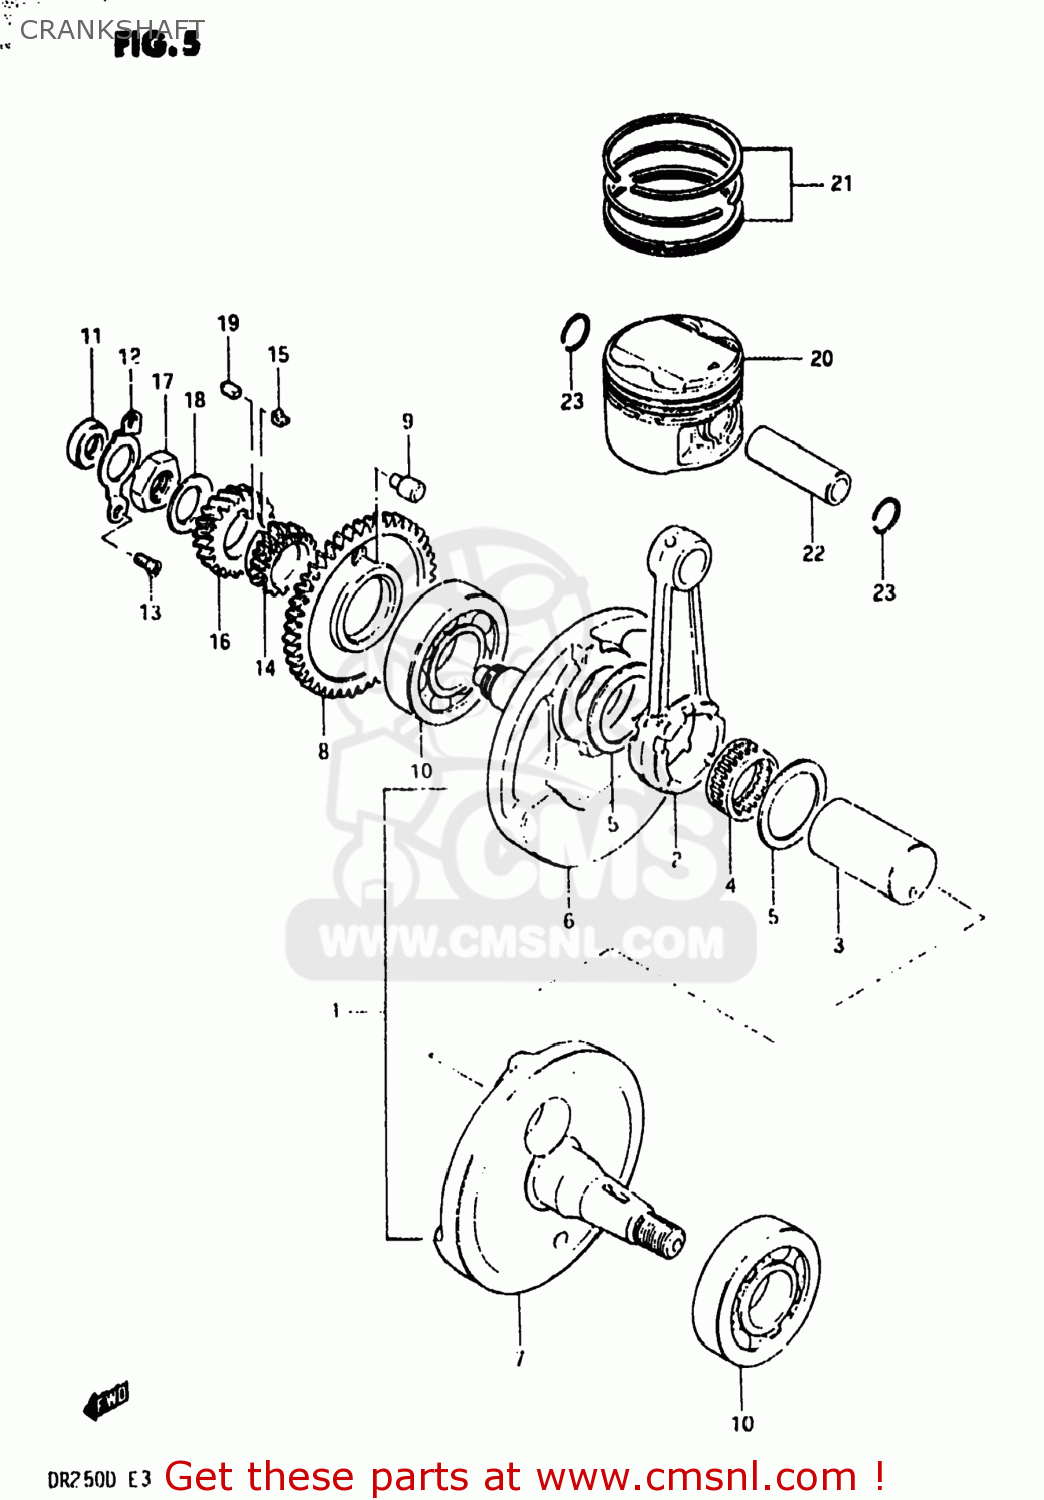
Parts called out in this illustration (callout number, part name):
1	CRANKSHAFT ASSEMBLY
2	CONNECTING ROD
3	PIN,CRANK
4	BEARING
5	WASHER(31X48.5X1)
6	CRANKSHAFT,R
7	CRANKSHAFT,LEFT
8	GEAR,CRANK BALANCER DRIVE
9	PIN
10	BEARING
11	SEAL,OIL(14X26X6)
12	RETAINER,CRANKSHAFT BEARING,R
13	SCREW
14	SPROCKET,CAM CHAIN DRIVE(NT:21
15	KEY,SPROCKET
16	GEAR,PRIMARY DRIVE NO.21
17	NUT (20MM)
18	WASHER
19	KEY
20	PISTON
21	RING SET,PISTON
22	PIN,PISTON
23	CIRCLIP
